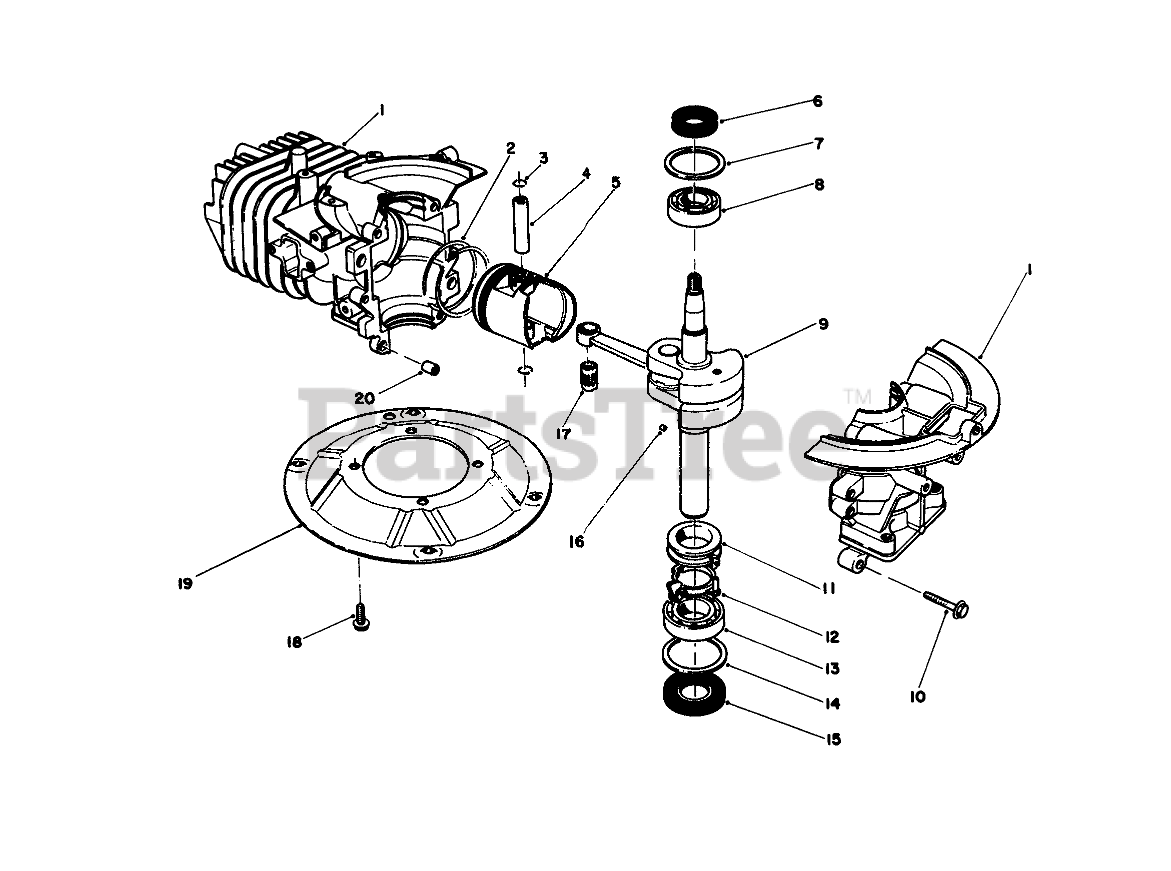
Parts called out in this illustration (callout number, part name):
1	CRANKCASE
2	RING SET
4	PIN-PISTON
5	Piston
6	OIL SEAL
7	WASHER-UPPER
8	BEARING-UPPER
9	Pin-Wrist
11	SPACER
12	BRACKET
13	LOWER BRG
14	WASHER-LOWER
15	SEAL-OIL
17	BEARING
19	PLATE-MOUNTING
